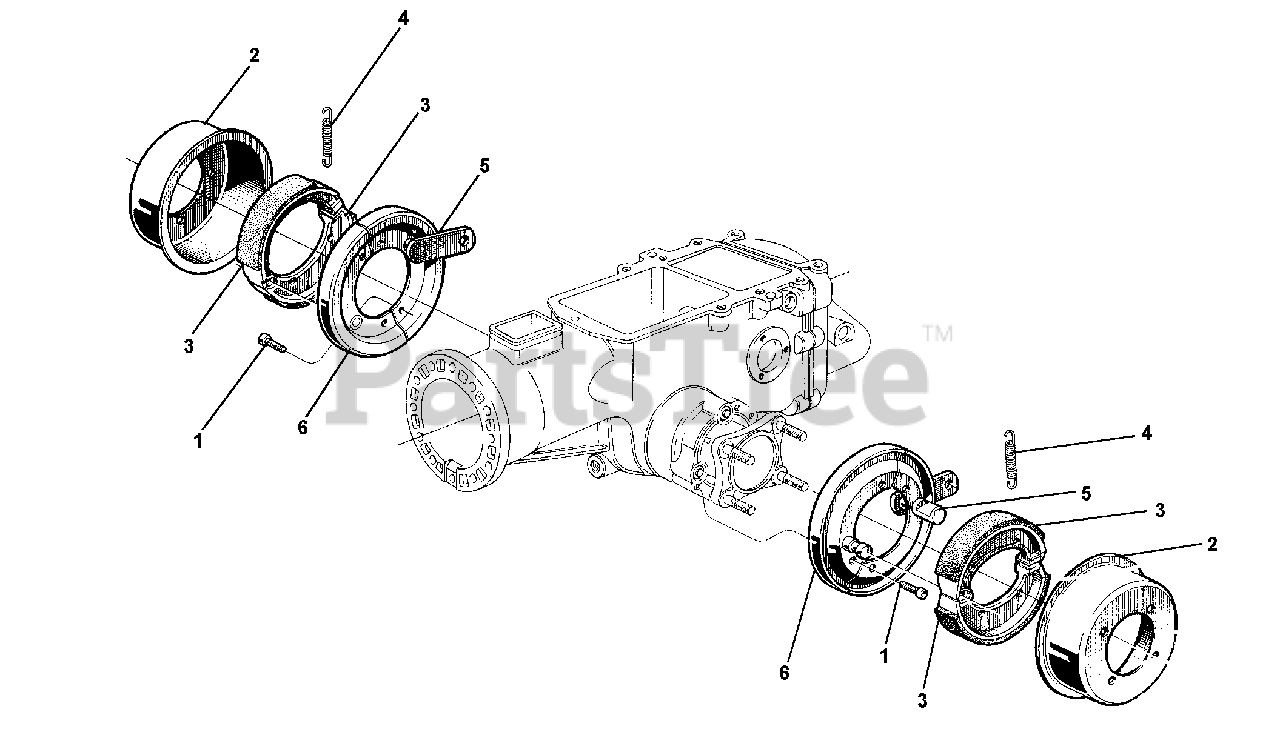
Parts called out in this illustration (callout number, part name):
1	SCREW TE CE M8 X 25
5	SEMIDISC LEVER
6	PIN HALF-DISC
